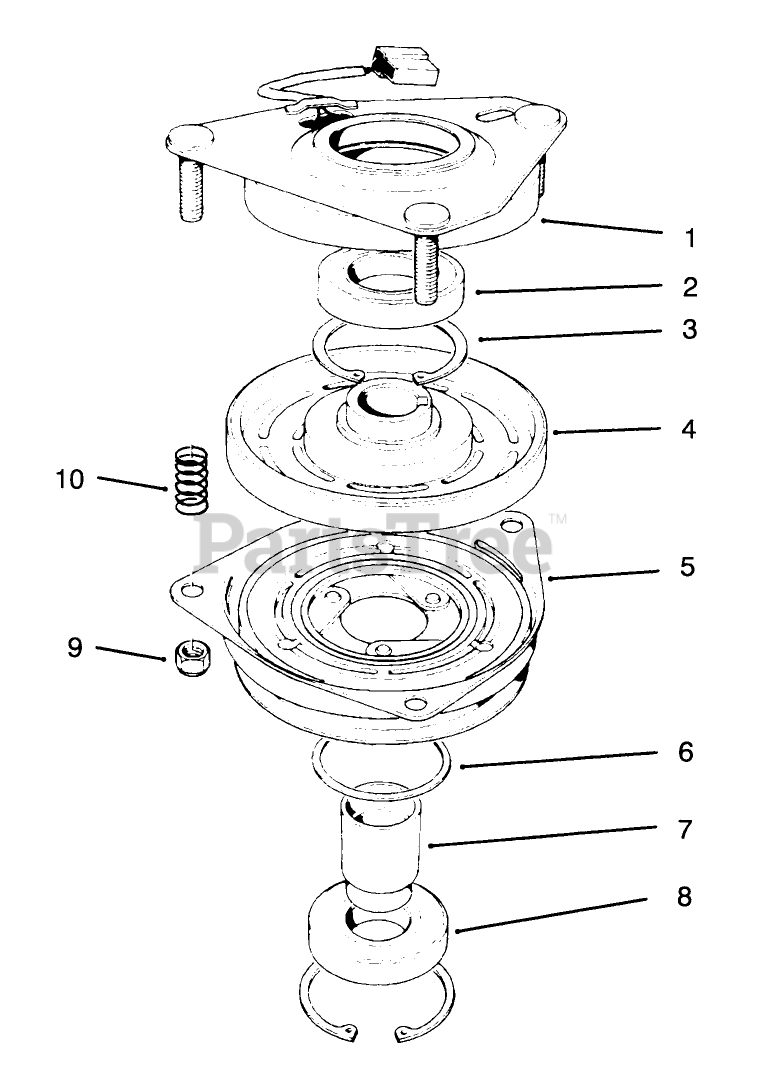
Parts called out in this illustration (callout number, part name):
1	FIELD BEARING ASM
2	BEARING-FIELD
3	RING-RETAINING
4	FIELD COIL/ROTOR BEARING ASM
6	SPACER-BEARING, PULLEY
7	COLLAR-BEARING
9	NUT-HEX
10	SPRING
